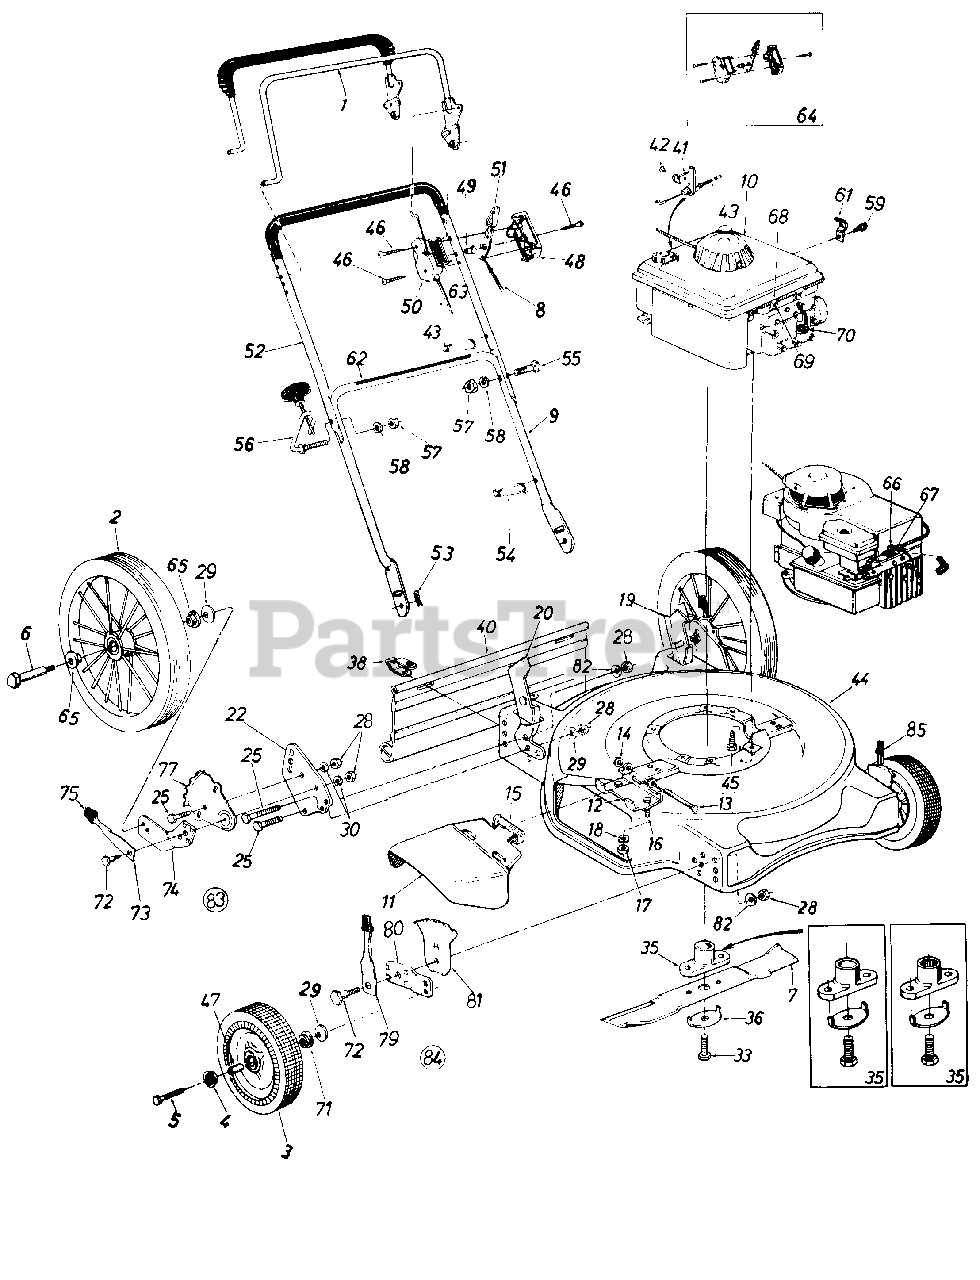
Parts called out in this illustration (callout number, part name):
1	Control Handle
2	Rear Wheel Ass'y.-Comp. 14.0 x 1.75
3	Front Wheel Ass'y.-Comp. 8.0 x 1.75
4	Bearing 1/2" I.D.
5	Front Axle Bolt
6	Rear Axle Bolt
7	22" Blade
8	Throttle Wire-53"
9	Lower Handle
10	Engine
11	Chute Deflector Ass'y. Comp.
12	Adapter Plate
13	Pivot Pin
14	Push Nut 1/41' Rod
15	Torsion Spring
16	Hex Bolt 1/4-20 x .50" Lg.*
17	Hex Nut 1/4-20 Thd.*
18	L-Wash. 1/4" I.D.*
19	Handle Mount Brkt.-L.H.
20	Handle Mount Brkt.-R.H.
22	Mounting Plate
25	Hex Bolt 3/8-16 x .75" Lg.
28	Hex Nut 3/8-16 Thd.*
29	Bell-Wash. .400" I.D. x .881"
30	L-Wash. 3/8" I.D.*
33	Hex Bolt 7/16-20 x 1.5" Lg.
35	Blade Adapter Kit (Splined)
36	Blade Bell-Wash.
38	Hinge Clip
40	Rear Flap Ass'y.
41	Cable Bracket
42	Pop Rivet
43	Control Cable-39"
44	22" Deck Ass'y.
45	Hex Wash. Hd. TT-Tap Scr. 3/8-16 x 1.00" Lg.
46	Truss Mach. "B"-Tap Scr. #12 x 1.50" Lg.
47	Spacer
48	Control Panel Half
49	Control Disc Pin
50	Clutch Panel Half
51	Throttle Control Lever
52	Upper Handle
53	Intern. Cot. Pin 5/16" Dia.
54	Cable Tie
55	Curved Carriage Bolt 5/16-18 x 1.38" Lg.
56	Rope Guide Bolt
57	Hex Nut 5/16-18 Thd.*
58	L-Wash. 5/16" I.D.
59	Hex B-Tap Scr. #10 x .381" Lg.
61	Cable Clamp
62	Instruction Label-Handle
63	Control Label-Throttle
64	Control Housing Comp.
65	Flange Bearing
66	Cable Clamp
67	Hex AB-Tap Scr. #8 x .38" Lg.
68	Casing Clamp
69	Hex B-Tap Scr. #10 x .62"
70	Spark Plug Boot
71	Ball Bearing 3/8" I.D.
72	Shoulder Bolt .50" Dia.
73	Spring Lever
74	Pivot Bar-R.H.
75	Spring Lever Knob
77	Index Plate
79	Spring Lever Ass'y. w/Knob
80	Pivot Bar
81	Height Adj. Plate
82	Bell-Wash. .39" I.D. x 1.38"
83	Rear Height Adj. Ass'y. Comp.-R.H.
84	Front Height Adj. Ass'y. Comp.-R.H.
85	Front Height Adj. Ass'y. Comp.-L.H .
